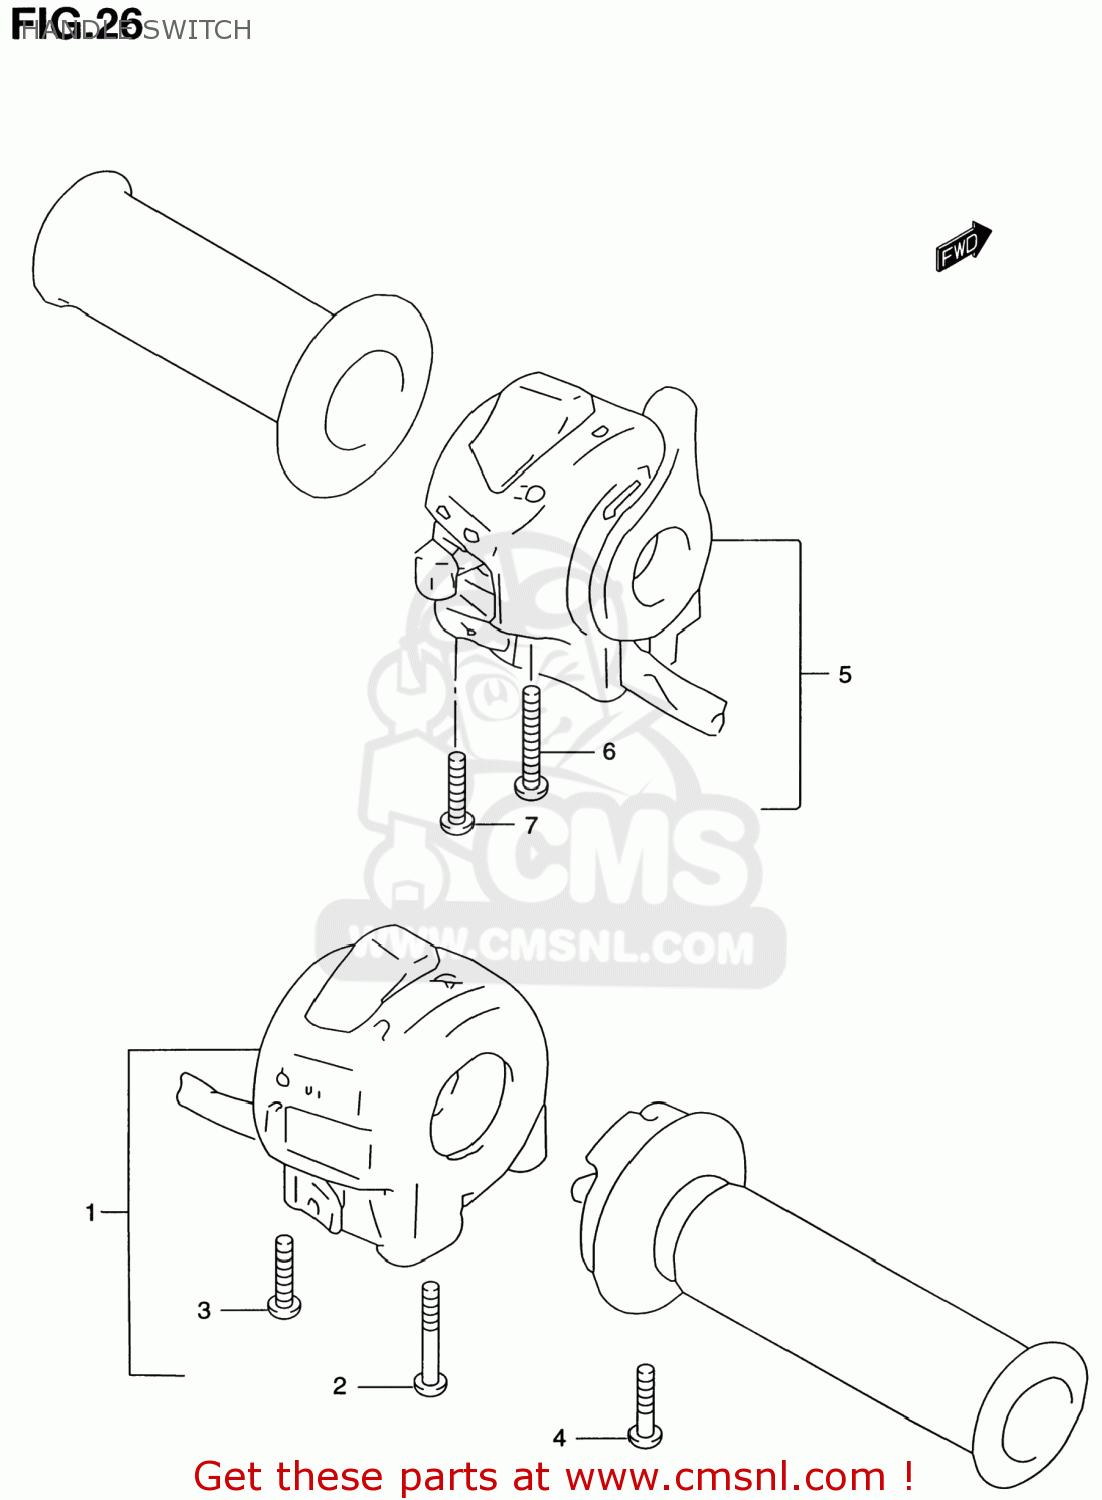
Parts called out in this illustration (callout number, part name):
1	SWITCH ASSY,HANDLE,R
2	SCREW
3	SCREW
4	SCREW
5	SWITCH ASSY,HANDLE,L
6	SCREW
7	SCREW
